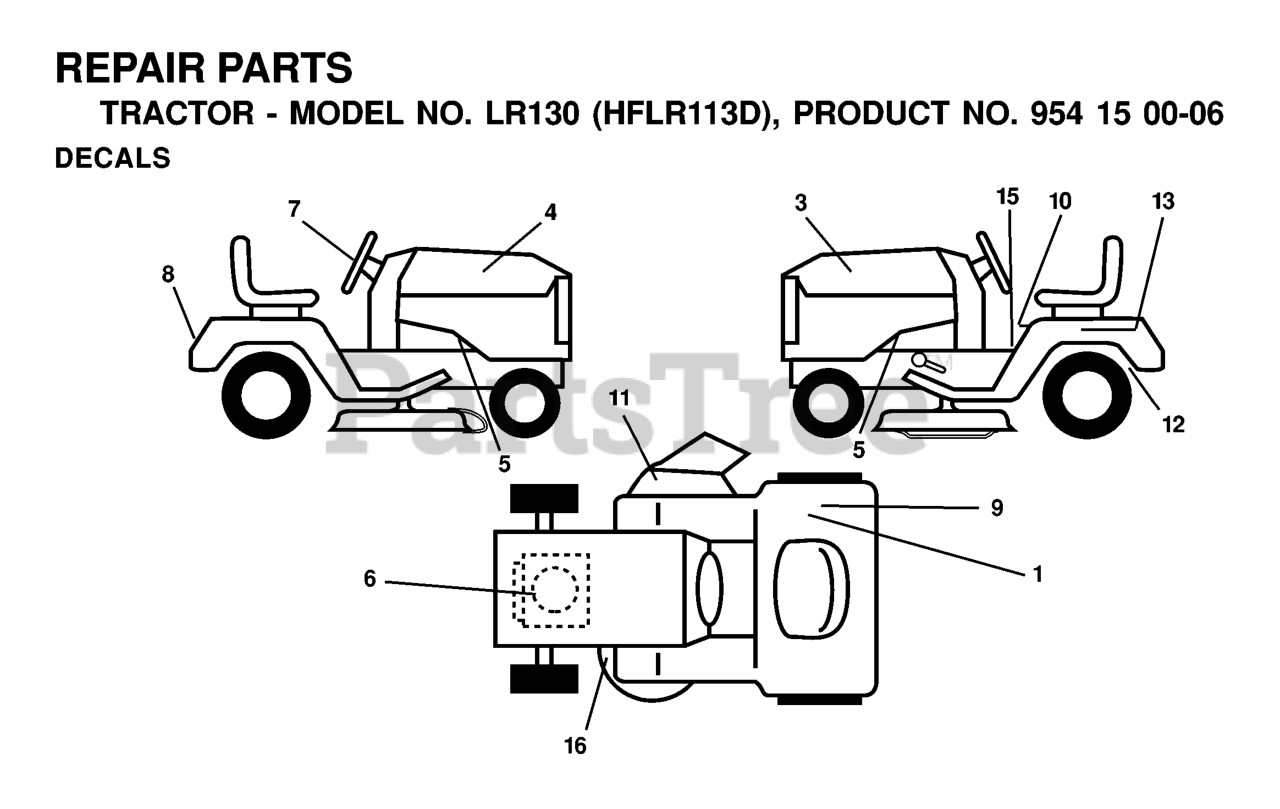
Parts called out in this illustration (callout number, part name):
1	DECAL EUROPE STANDARD CE
8	DECAL FENDER HUSQ
9	DECAL CERTIFICATION
10	DECAL READ OWNER'S MAN SYMS
11	DECAL MOWER CUT/FINGER
12	DECAL
13	DECAL BTRY SYMBOLS
15	Decal, Brake/Clutch Symbols
